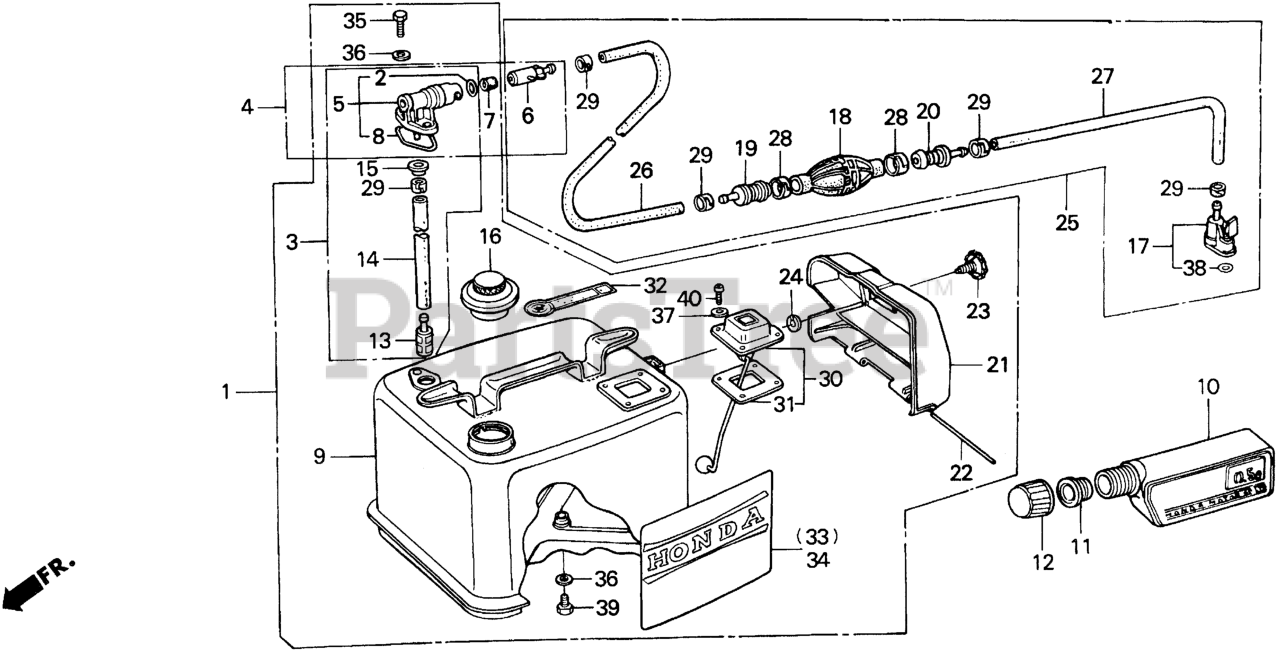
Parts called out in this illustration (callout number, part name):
1	TANK KIT, FUEL *R8* (BRIGHT RED) (NOT AVAILABLE)
3	JOINT A, FUEL
4	JOINT, FUEL CONSENT
5	JOINT A, FUEL CONSENT
6	JOINT B, FUEL CONSENT
7	ABSORBER, FUEL
8	RING, PETCOCK SEAL
9	TANK, FUEL *R8* (BRIGHT RED) (NOT AVAILABLE)
9	TANK, FUEL *R8* (BRIGHT RED)
10	TANK, OIL
11	CAP, SUB-TANK (INNER) (NOT AVAILABLE)
12	CAP, SUB-TANK
13	FILTER, FUEL
14	TUBE (INNER)
16	CAP, FUEL FILLER (NOT AVAILABLE)
16	CAP, FUEL FILLER
17	CONNECTOR, FUEL *NH1* (BLACK)
18	BULB, PRIMER
19	VALVE, IN.
20	VALVE, OUTLET
21	BOX, TOOL (NOT AVAILABLE)
21	BOX, TOOL
22	BAR (3X150) (NOT AVAILABLE)
23	LATCH, TOOL BOX (NOT AVAILABLE)
24	STOPPER, LATCH (NOT AVAILABLE)
25	TUBE, FUEL *B9* (ATLANTIS BLUE) (NOT AVAILABLE)
25	TUBE, FUEL *NH1* (BLACK)
26	TUBE, FUEL LONG (NOT AVAILABLE)
26	TUBE, FUEL LONG
27	TUBE, FUEL SHORT
28	BAND, TUBE CLIP (20MM)
29	BAND, TUBE CLIP (11MM)
30	METER ASSY., FUEL
31	GASKET (NOT AVAILABLE)
31	GASKET, FUEL METER
32	MARK, TANK CAUTION (ENGLISH/FRENCH)
33	MARK B, TANK (ENGLISH)
34	MARK, TANK (FRENCH)
35	BOLT, FLANGE (6X16)
36	GASKET, FIBER (6MM)
37	GASKET, FIBER (5MM)
38	O-RING (5.5MM)
39	BOLT, HEX. (6X12)
40	SCREW, PAN (5X8)
40	SCREW, PAN (5X10)
